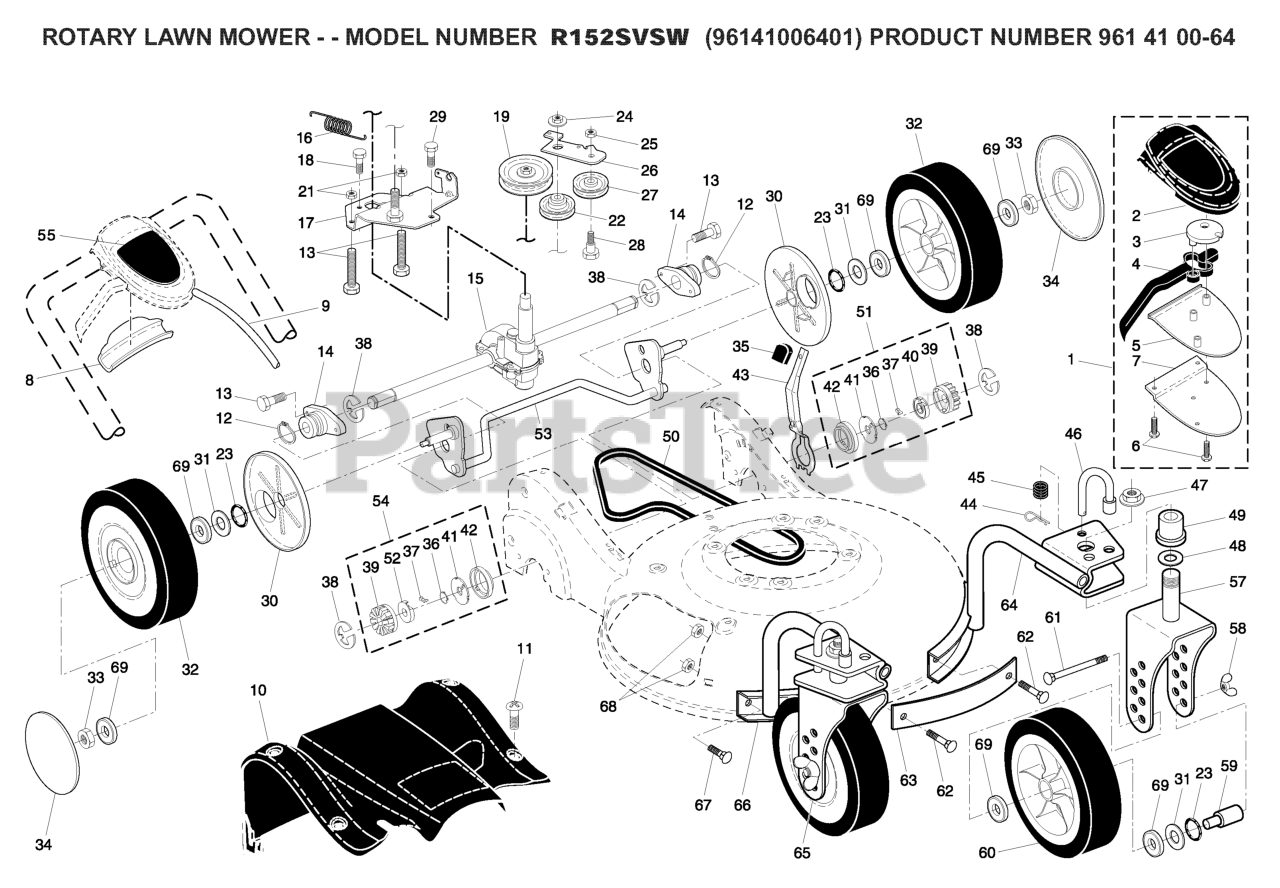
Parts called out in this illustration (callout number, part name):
1	CONTROL.DR.HV.RWGD.GRY/BLU
2	CASE.TOP.GRAY
3	PULLEY.CAM.DRIVE.CONTROL.HV
4	LEVER
5	CASE BOTTOM
6	SCREW, PHILLIPS HEAD 10 X 5/8
7	BRACKET, DRIVE CONTROL
8	BRACKET.DRIVE.CONTROL.MOUNT.BL
9	ASM.CABLE.
10	COVER ASM. DRIVE
12	RETAINING RING (2 2)(3 2)
13	SCREW.1/4-20X21/4.HEX.
14	BEARING.SUPPORT.ASSEM
15	TRANSMISSION.21.HI-VAC.EZ
16	SPRING.RETURN
17	BRKT.TRANSMISSION.HV.E
21	NUT
22	PULLEY.IDLER.V-BELT
23	O-RING
24	NUT
25	NUT.CENTERLOCK.5/16-
26	ARM.IDLER.BZP
27	IDLER PULLEY
28	SHOULDER BOLT
29	SCREW 14-20 X 5/8
30	DUST COVER, WHEEL
31	WASHER.FLAT.1/2
32	WHEEL.9X2.25.PR.JUNG.BLK
33	HEX FLANGE LOCKNT
34	RB HUBCAP.3-SPOKE.SILVER
35	KNOB.SELECTOR.SPRG.H-GRY (2 2)
36	SPRING, TORSION
37	PAWL.DRIVE.21.EZ-WALK
38	E-RING 7/16 RE
39	GEAR, PINION
40	RETAINER.DRIVE.21.EZ-WALK.LT
41	DISC.DRIVE.21.EZ-WALK
42	SEAL.PINION
43	LEVER, SELECTOR, HEIGHT, REAR
44	COTTER PIN (3 2)(2 2MC)
48	WASHER.FLAT.1/2
50	BELT.DRIVE.EZ.WALK.HI-VAC
51	PINION ASSY, LH
52	RETAINER, DRIVE, RH
53	AXLE.ASM.REAR.TORQUE.BZP
54	PINION ASSY, RH
55	DECAL, DRIVE
57	BRACKET, CASTER WHEEL, RH
58	NUT.WING.5/16-18.YELLOW
60	WHEEL.9X2.25.LP.JUNG.SILV.BB.1
61	CARRIAGE BOLT
63	STRAP.FRONT.CASTER.ORANGE
64	SUPPORT TUBE ASSY, LH
65	BRACKET, CASTER WHEEL, LH
66	SUPPORT TUBE ASSY, RH
68	NUT
69	BEARING.8".WHEEL
